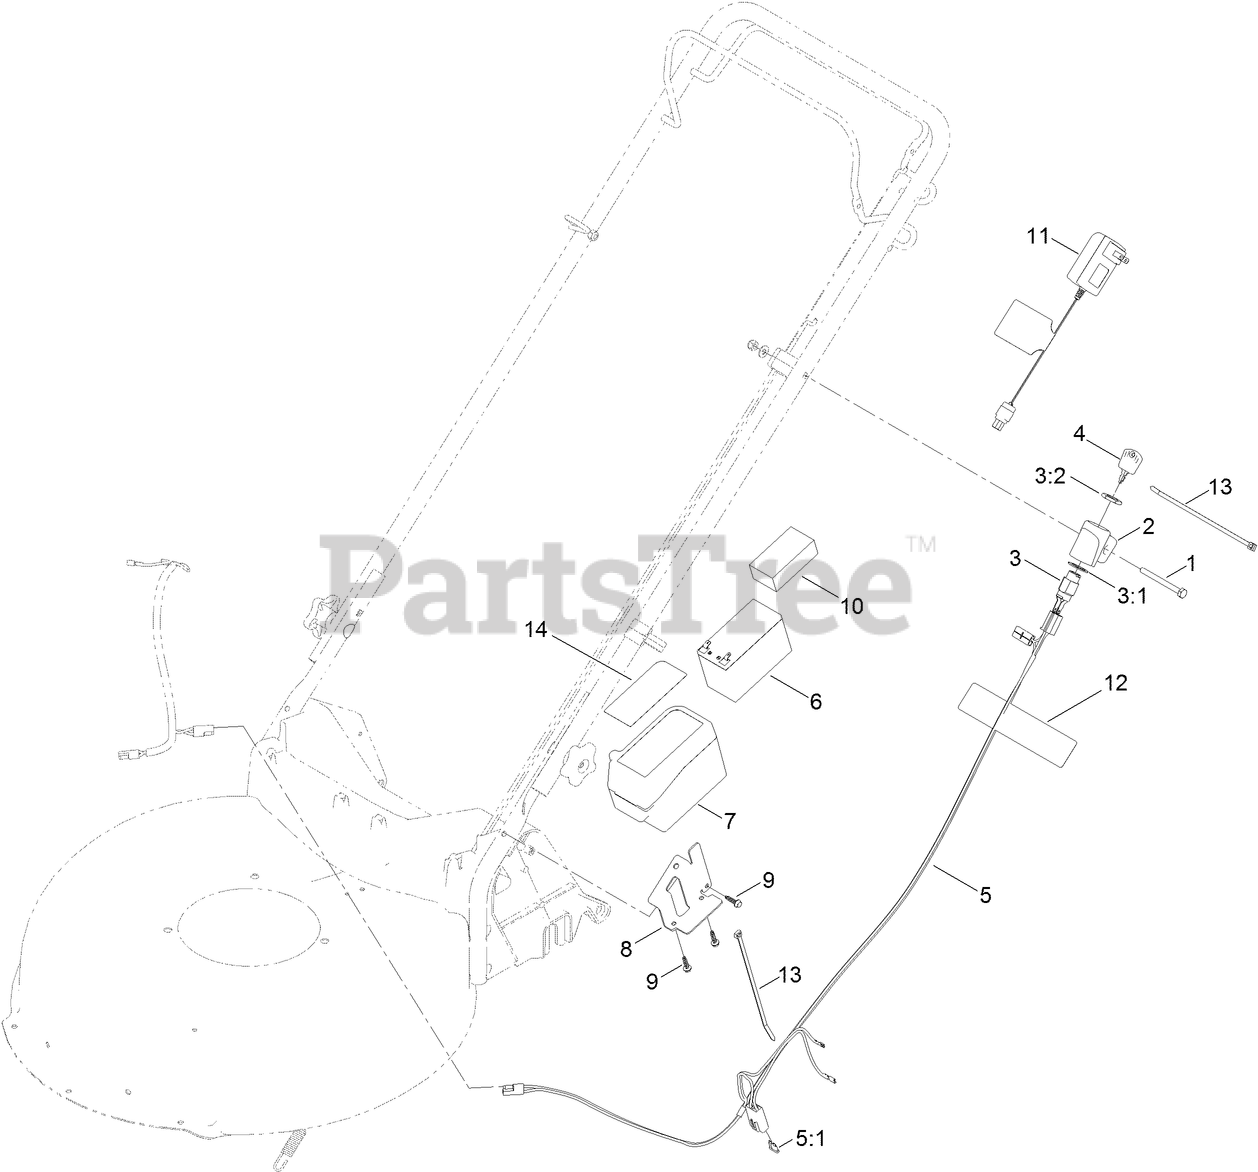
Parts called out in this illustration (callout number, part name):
1	SCREW-HH
2	MOUNT-SWITCH
3	STARTER SWITCH ASM
3:1	WASHER-LOCK
5	HARNESS-WIRE
5:1	FUSE-40 AMP
6	BATTERY-NONSPILLABLE, 12 V
7	BATTERY BOX ASM
8	BRACKET-BATTERY
9	SCREW-HWH
10	FOAM-BATTERY, TOP
11	CHARGER, BATTERY (12V)
12	DECAL-WARNING
13	TIE-CABLE
